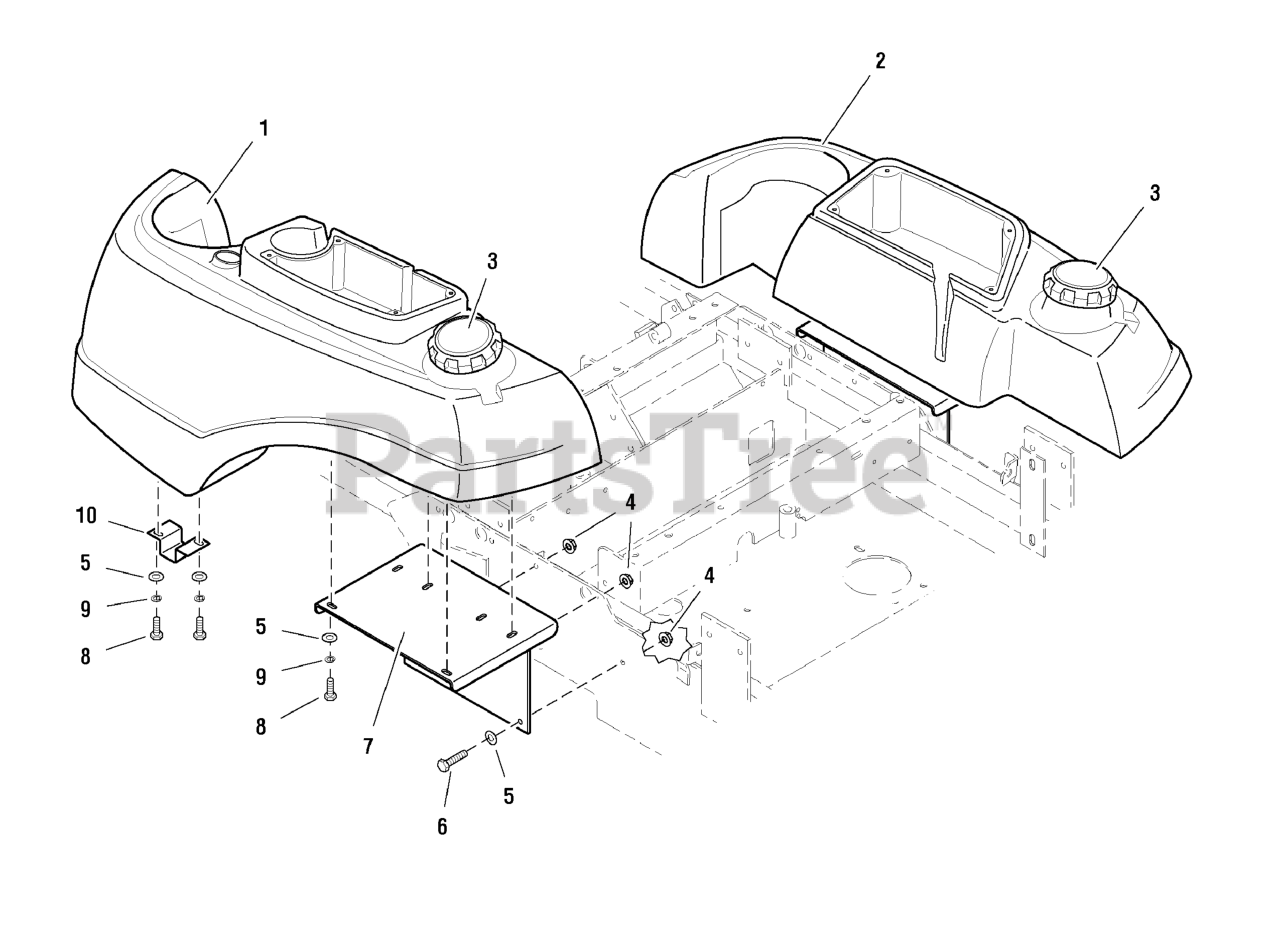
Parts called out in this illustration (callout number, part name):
1	FUEL TANK, IS5000Z, LH
2	FUEL TANK, IS5000Z, RH
3	FUEL TANK CAP, DIESEL
4	NUT, 5/16-18 HEX SERRATED FLANGE (LARGE)
5	WASHER, 5/16" SAE
6	BOLT, 5/16-18 X 1 GD5 YZ
7	FUEL TANK MOUNT
8	BOLT, 5/16-18 X 3/4 GD5
9	WASHER, 5/16 LOCK CZ
10	GUARD, Tank Valve
